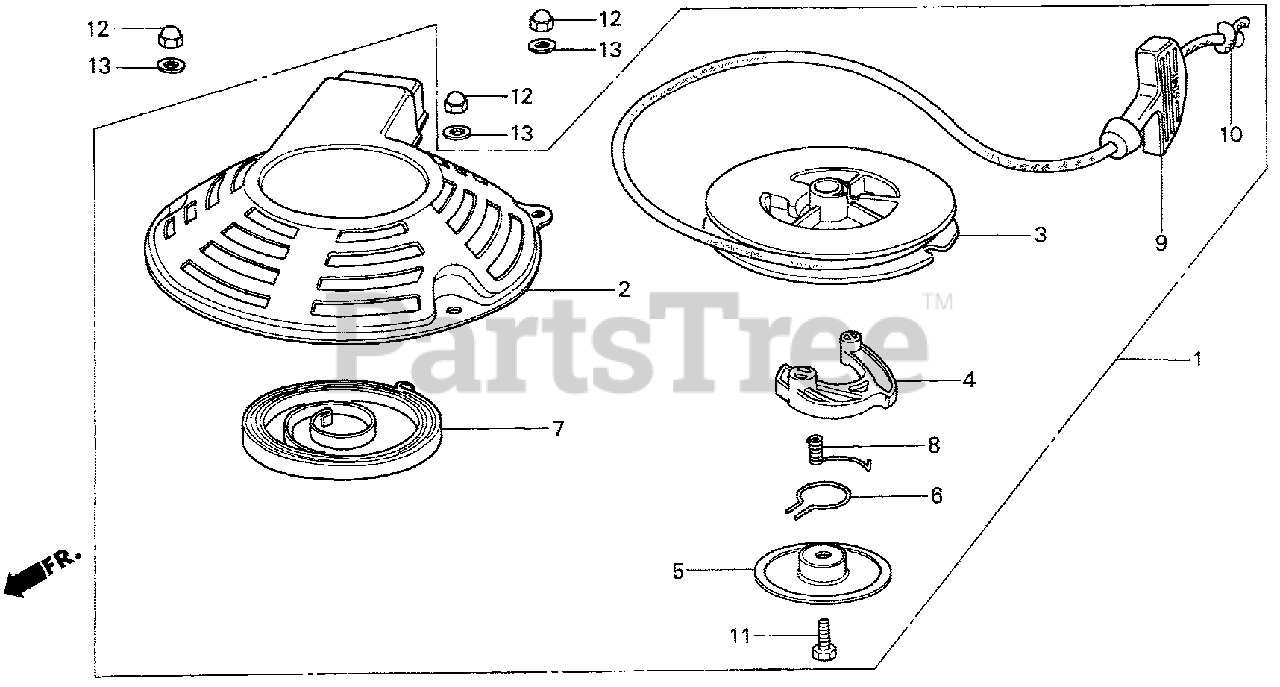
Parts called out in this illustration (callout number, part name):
1	STARTER ASSY., RECOIL (NOT AVAILABLE)
2	CASE, STARTER (NOT AVAILABLE)
3	PULLEY, RECOIL STARTER (NOT AVAILABLE)
4	RATCHET, STARTER
5	PLATE, FRICTION
6	SPRING, FRICTION
7	SPRING, RECOIL STARTER
8	SPRING, RETURN
9	GRIP, STARTER (NOT AVAILABLE)
10	ROPE (#4X91")
11	BOLT, HEX. (6X12)
12	NUT, CAP (5MM)
13	WASHER, PLAIN (5MM)
